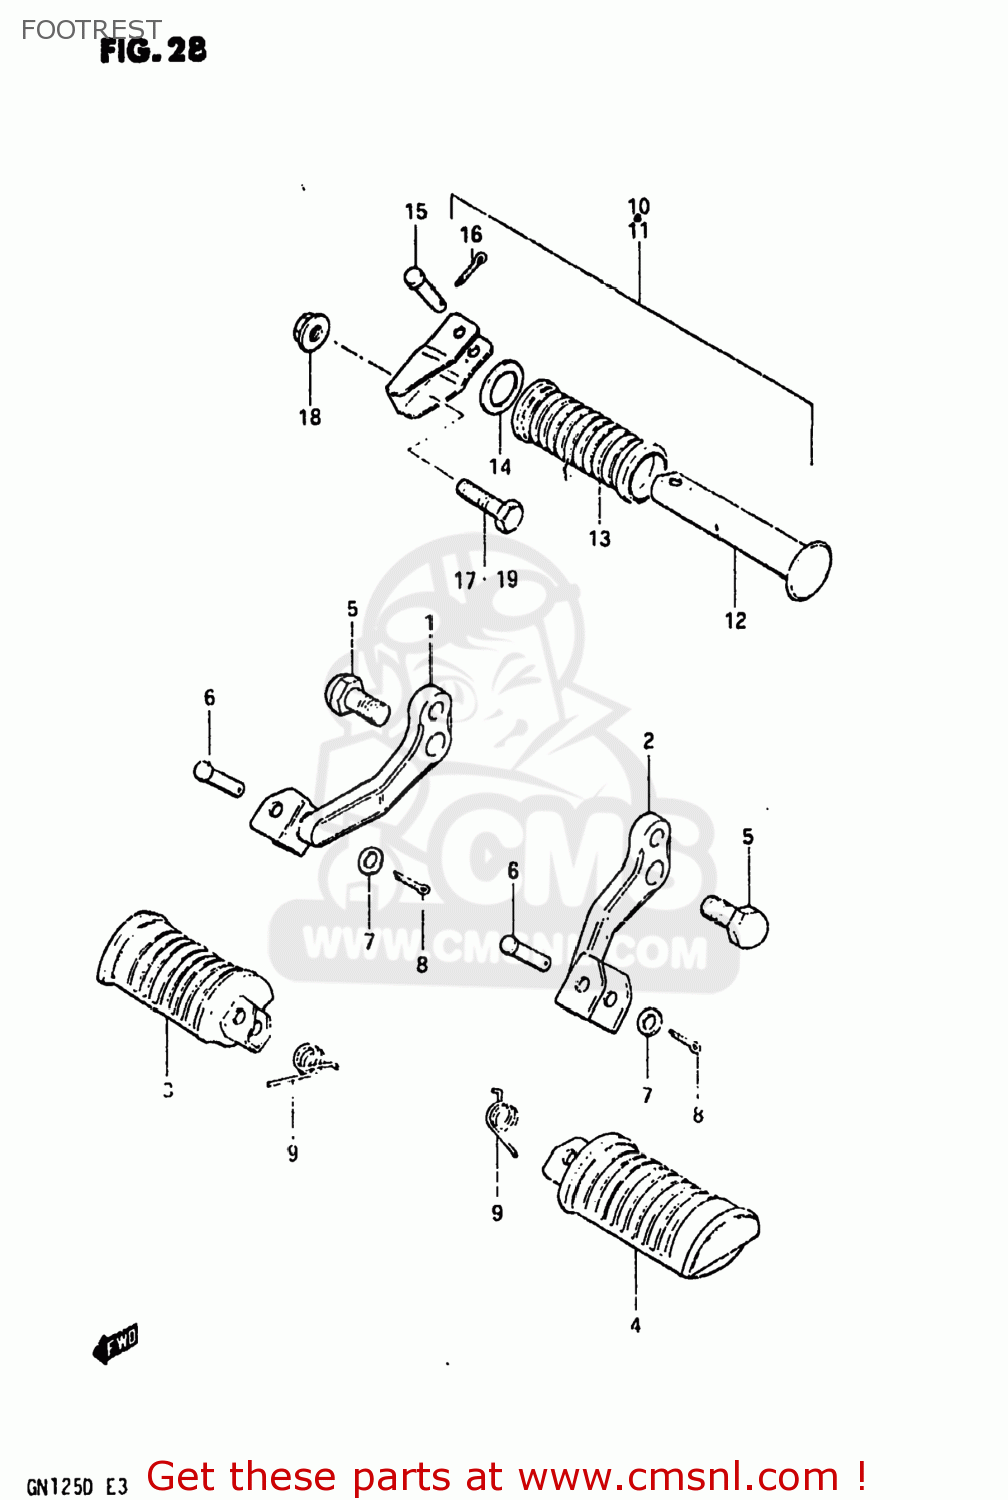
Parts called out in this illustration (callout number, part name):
1	HOLDER,FR FOOTREST,R
2	HOLDER,FR FOOTREST,L
3	RUBBER,PILLION FOOTREST,R
4	RUBBER,PILLION FOOTREST,L
5	BOLT
6	PIN
7	WASHER
8	PIN 20X20
9	SPRING
10	FOOTREST ASSY,PILLION,R
11	FOOTREST ASSY,PILLION,L
12	BAR,FOOTREST RUBBER
13	RUBBER,PILLION FOOTREST
14	WASHER (19.5X32X2)
15	PIN
16	PIN
17	BOLT 10X45
18	NUT
19	BOLT
